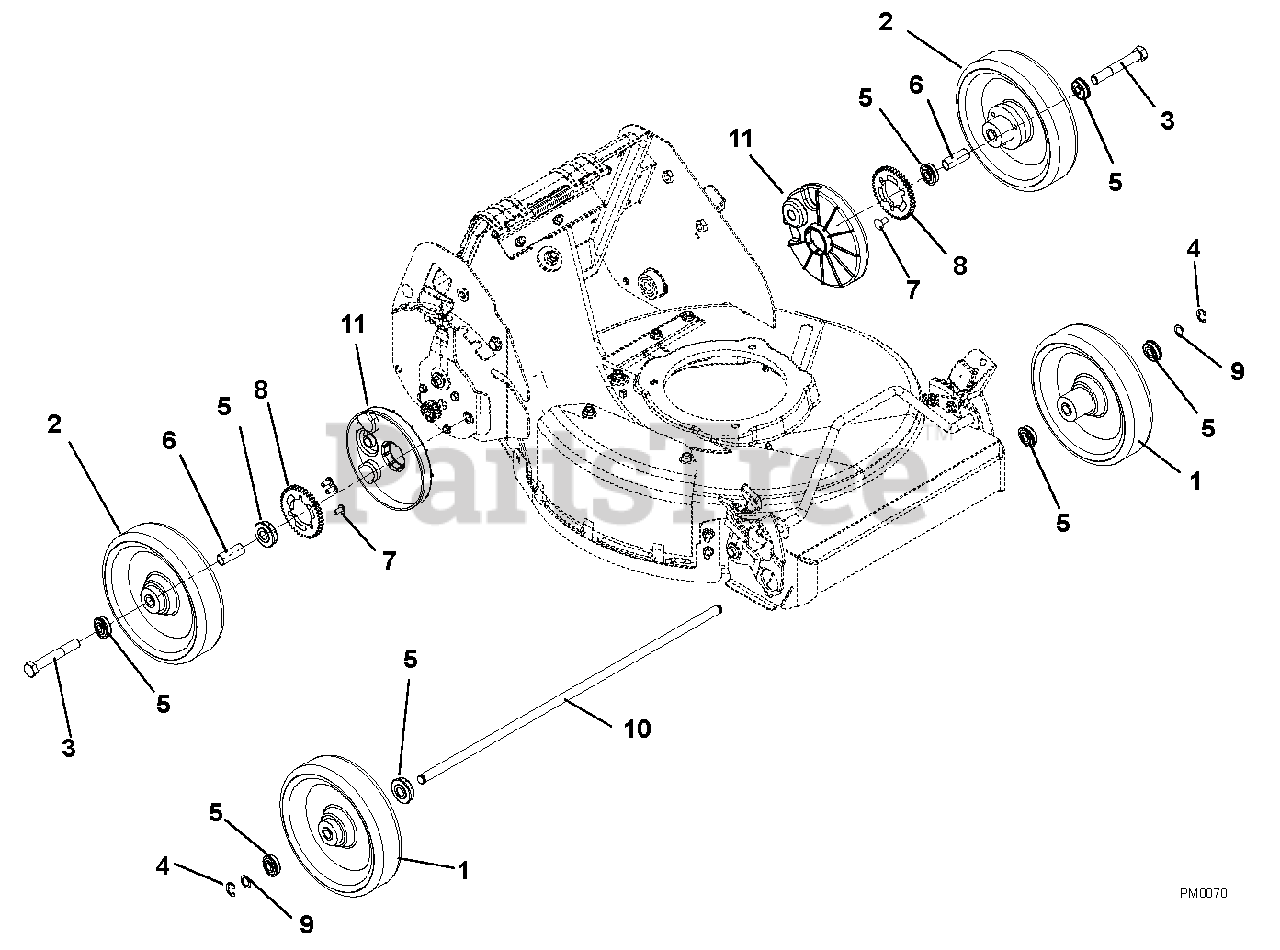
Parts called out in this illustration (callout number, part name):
1	TIRE, 8 X 1.75 COMMERCIAL FRNT
2	WHEEL, REAR
3	BOLT,5/8 SHLDR,1/2-13 GR8,YWZC
4	RG-RTNG-EXT .500X.042 (E)
5	BRG-BALL .50X1.375X.437 SEALED
6	SPACER,.560 ID X.750 OD X 2.09
7	SCR-TAP 1/4-20X3/4 LPAN TL BZ
8	GEAR, WHEEL
9	WASHER, .500X.750X.020 THRUST
10	AXLE, HD21 FRONT
11	COVER, WHEEL
